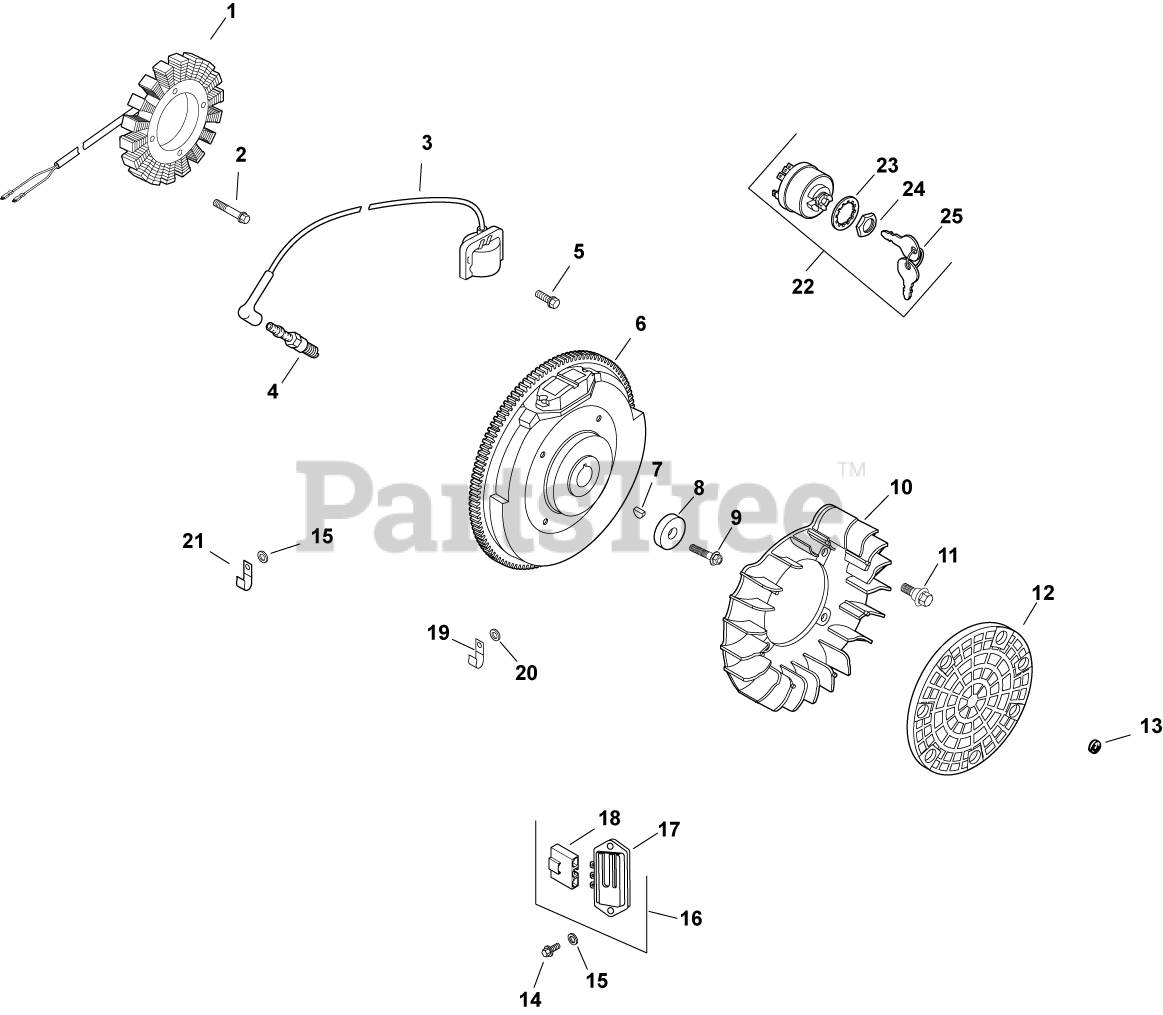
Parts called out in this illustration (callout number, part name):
1	KIT, 25 AMP STATOR ASSY.
2	SCREW, THD FROM M5X0.8X30
3	KIT, MODULE IGNTN (CDI FIXED)
4	PLUG, SPARK (STD)
5	SCREW, FLG THD FRM M5X.8X20-(#25086399S)
6	FLYWHEEL, PAINTED-USE 24 025 55-S
7	KEY, 3/16" X 5/8"
8	WASHER, FLAT 13/32"
9	SCREW, FLG M10X1.5X45 - (#25086361S)
10	FAN - USE (#24 157 11-S)
11	BOLT, SHOULDER
12	SCREEN, GRASS
14	SCREW, PHL HD #11-16X7/8"
15	WASHER, FLAT 7/32"
16	KIT, FULL WAVE CONVERSION
17	REG/RECTIFIER (20/25 AMP)-USE 25 403 20-
18	CONNECTOR, BODY (KM)-USE 25 155 41-S
19	CLIP, TUBE & WIRING (KM)
20	WASHER, FLAT 1/4" (O.D. 1/2")
21	CLIP, CABLE
22	SWITCH ASSY, KEY (KM)-USE 25 099 32-S
23	WASHER, INTERNAL TOOTH
24	NUT, KEY SWITCH
25	KEY, SET -USE 48 340 01-S
